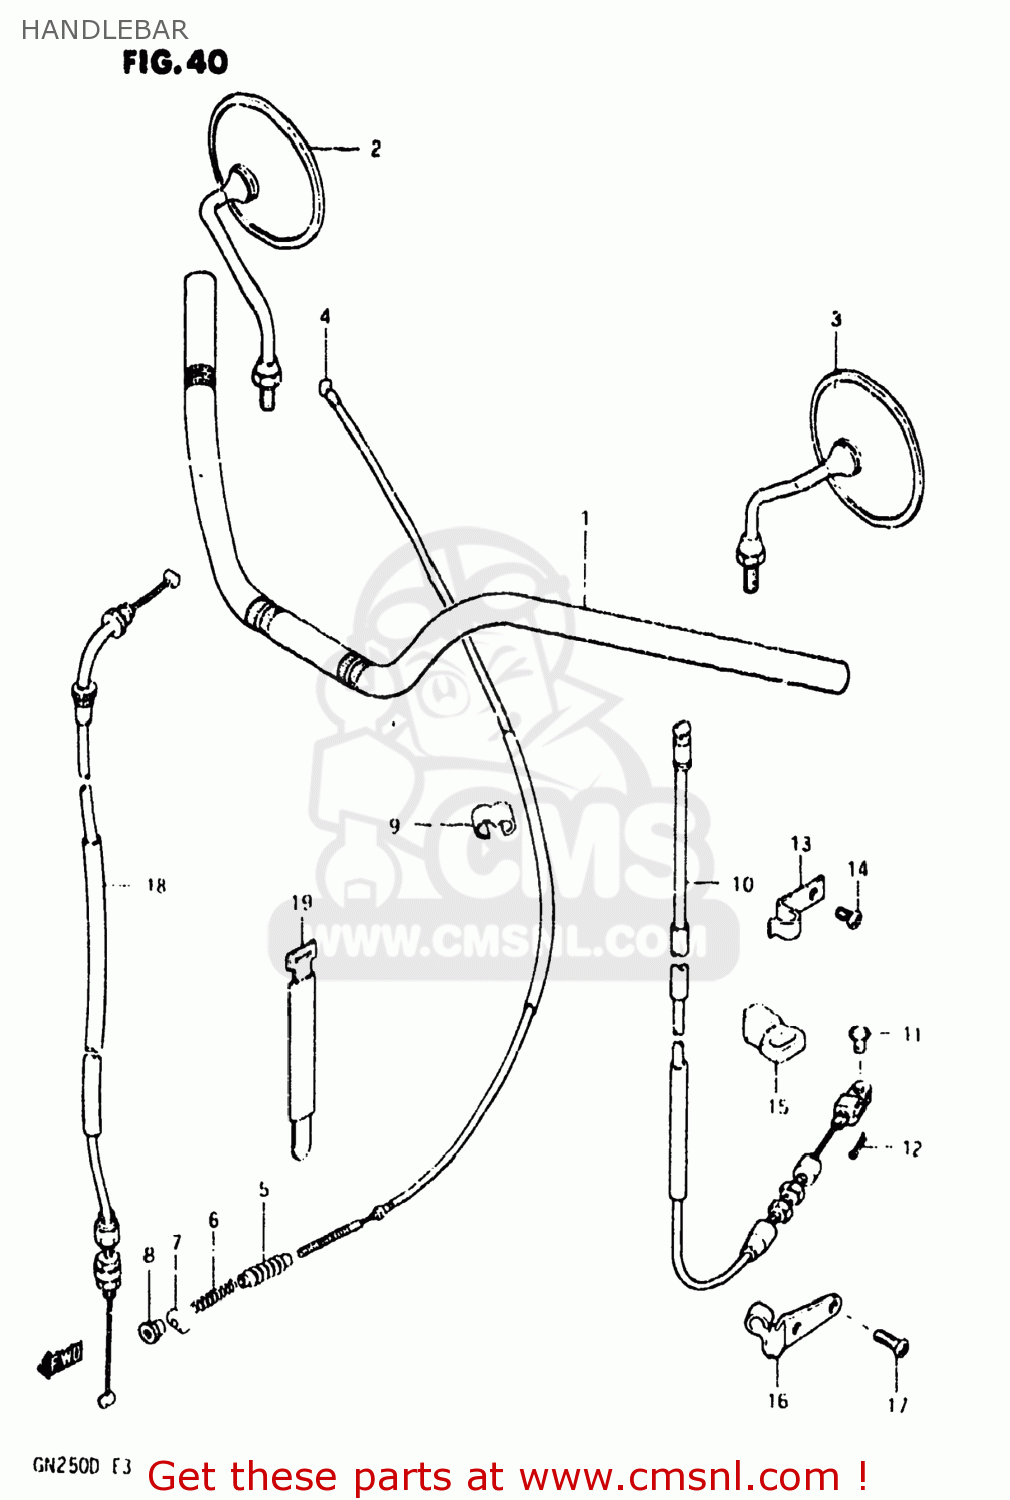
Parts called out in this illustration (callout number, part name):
1	HANDLEBAR
2	MIRROR ASSEMBLY,RIGHT
3	MIRROR ASSEMBLY,LEFT
4	CABLE ASSEMBLY,FRONT BRAKE
5	SEAL,DUST(8X17X72)
6	SPRING
7	PIN
8	NUT (6MM)
9	CLIP
10	CABLE ASSEMBLY,CLUTCH
11	PIN(L:13)
12	PIN
13	CLAMP,CLUTCH CABLE NO.1
14	SCREW
15	GUIDE,CLUTCH CABLE
16	STOPPER,CLUTCH CABLE
17	SCREW 6X12
18	CABLE ASSEMBLY,THROTTLE
19	CLAMP(L:250)
